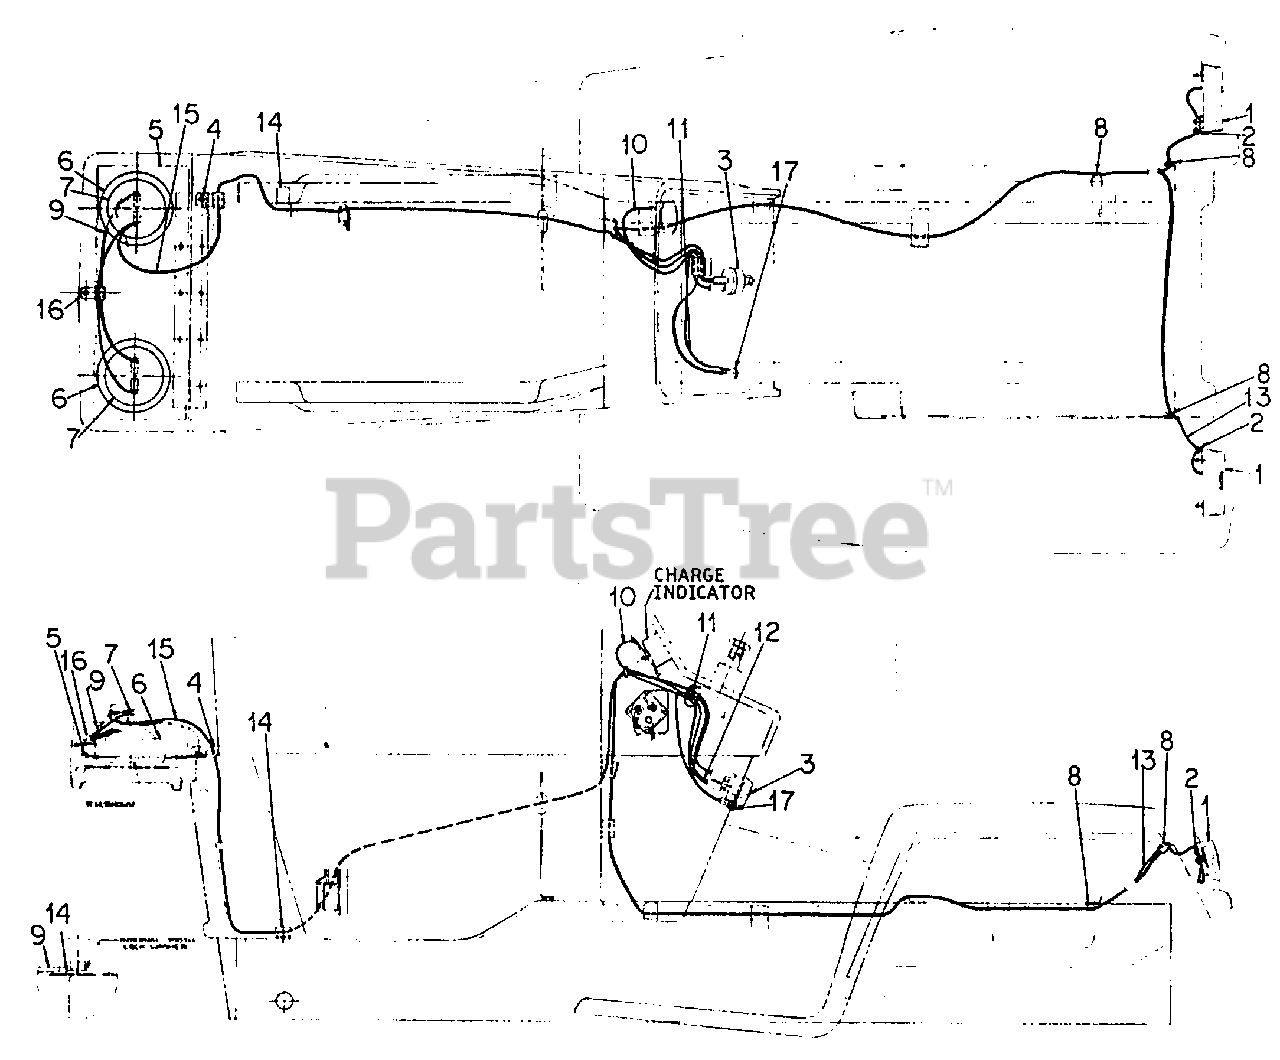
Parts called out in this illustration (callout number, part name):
1	Taillight Assy
2	Clip, Taillight
3	Switch, Lighting
4	Clip, Taillight Cable
5	Panel, Headlight Mounting
6	Rim, Headlight
7	Unit Assy, Headlight Sealed Beam
8	Clip, Cable
9	Cable, Headlight to Ground
10	Cable, Charge Indicator to Fuse
11	Cable, Fuse to Lighting Switch
12	Cable, Lighting
13	Cable, Taillight
14	Clip, Cable
15	Cable Assy, Headlight
17	Holder Assy, Fuse
